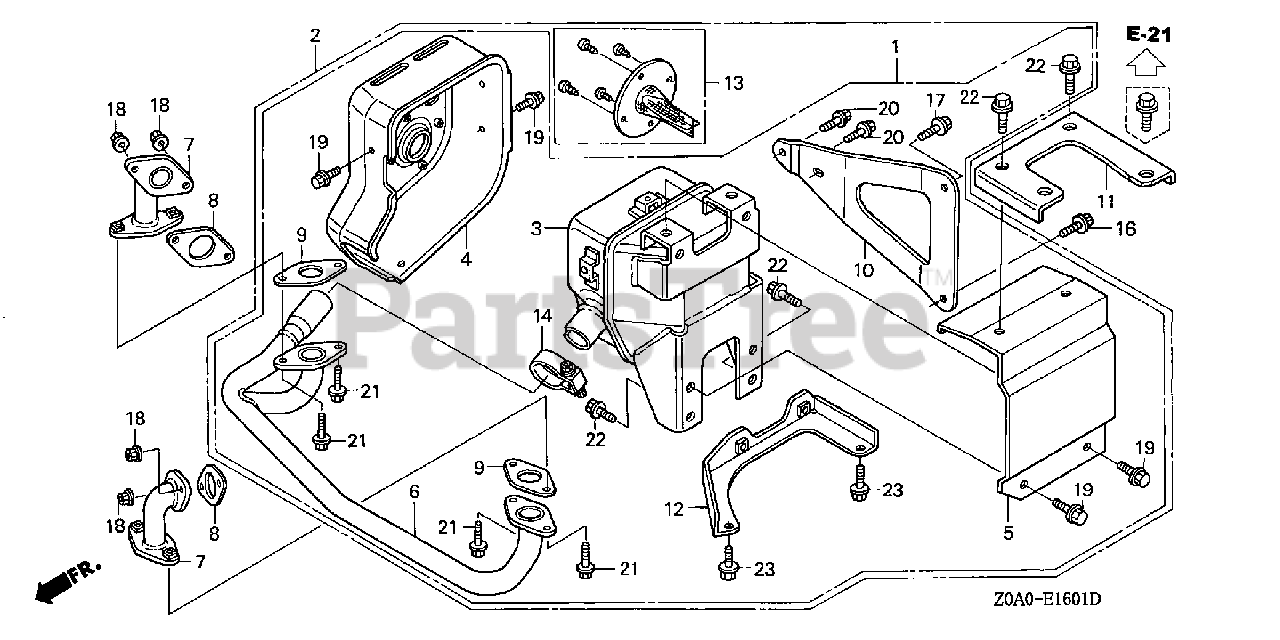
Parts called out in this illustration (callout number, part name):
1	MUFFLER KIT (A)
2	MUFFLER KIT (B)
3	MUFFLER
4	PROTECTOR, MUFFLER (SIDE-L)
5	PROTECTOR, RR. MUFFLER
6	PIPE, EX.
7	PIPE, EX. (FLANGE)
8	GASKET, EX. PIPE
9	GASKET, EX. PIPE
10	BRACKET, MUFFLER
11	BRACKET, MUFFLER (UPPER)
12	BRACKET, MUFFLER (LOWER)
13	ARRESTER, SPARK (SIDE)
14	BAND ASSY.
16	BOLT, FLANGE (6X14)
17	BOLT, FLANGE (6X20)
18	NUT, FLANGE (6MM)
19	BOLT, FLANGE (6X8)
20	BOLT, FLANGE (6X10)
21	BOLT, FLANGE (6X16)
22	BOLT, FLANGE (8X14)
23	BOLT, FLANGE (8X35)
